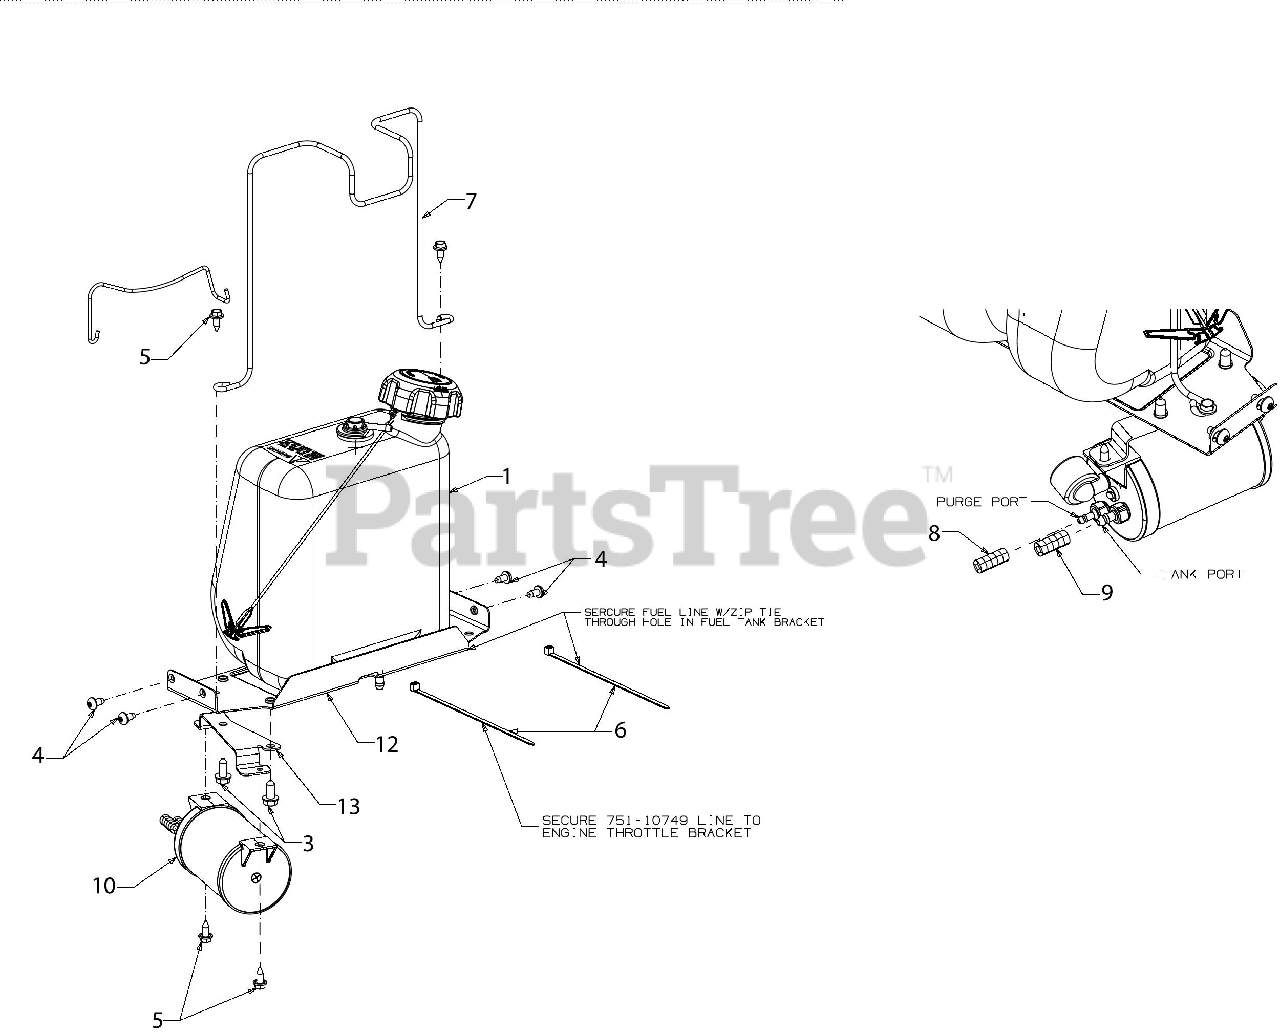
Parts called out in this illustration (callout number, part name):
1	FUEL TANK ASSEMBLY
2	BATTERY ROD ASSEMBLY
3	SCREW 5/16-18 x .750
4	SCREW 1/4-20 x .5
5	SCREW 1/4-20X.625
6	7" CABLE TIE
7	FUEL TANK SUPPORT ROD -
8	FUEL HOSE LO PERMEATION
9	FUEL HOSE LO PERMEATION
10	CARBON CANISTER
11	FUEL CAP W/TETHER
12	FUEL TANK BRACKET
